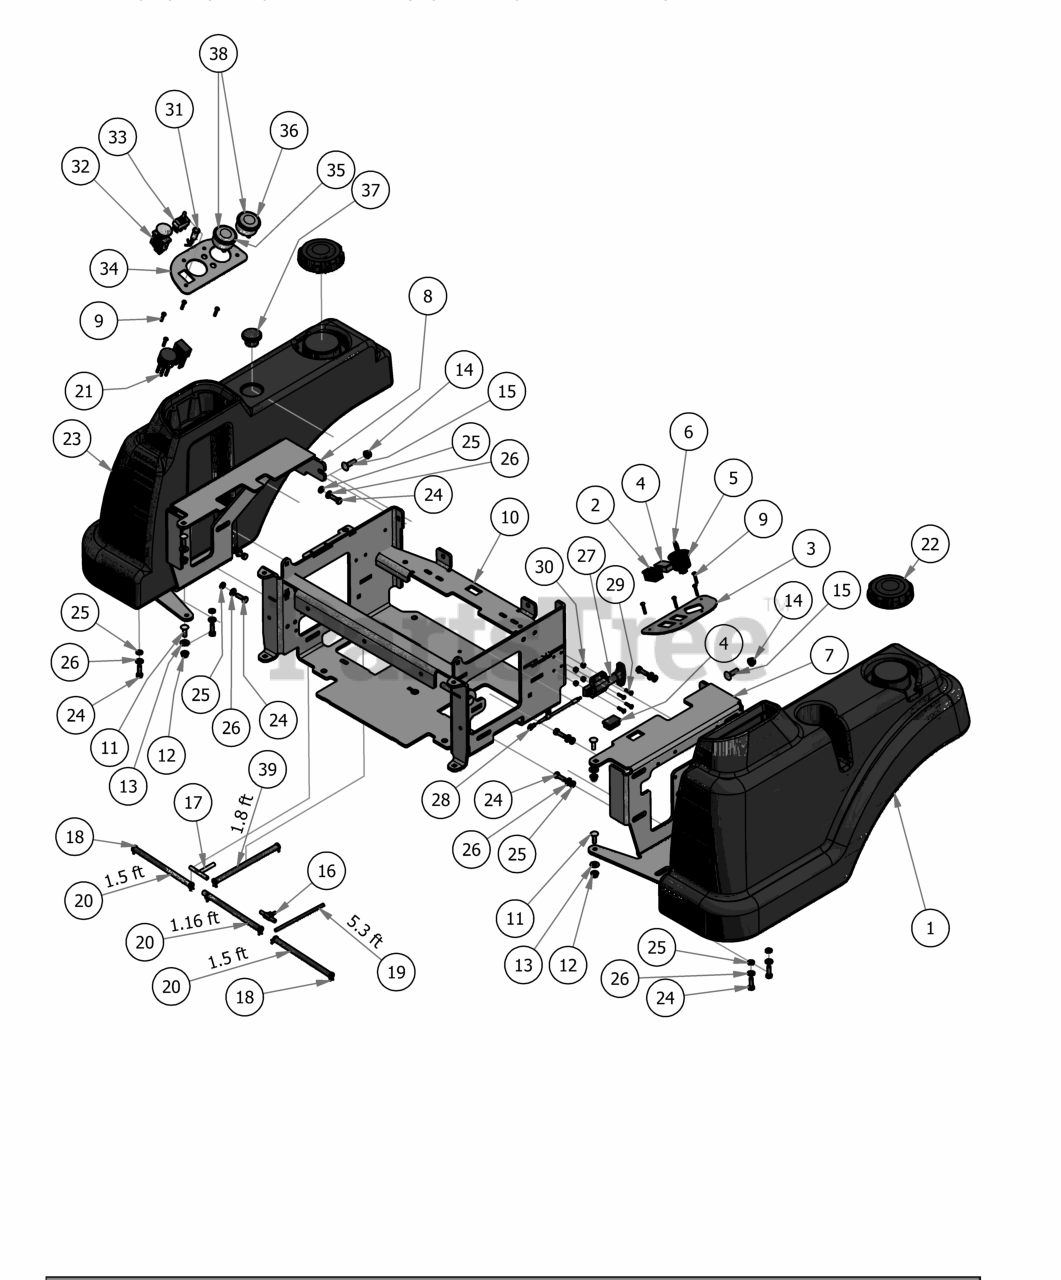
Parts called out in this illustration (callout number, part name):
1	Left Fuel Tank with Fender
2	Hour Meter
3	Control Panel (Left)
4	Light Plug
5	Ignition Switch
6	Ignition Key
7	Left Tank Support
8	Right Tank Support
9	10-32 x 1 Button Head Bolt
10	Diesel Seat Frame
11	5/16" x 1" Carriage Bolt
12	5/16" Flange Nut
13	.360 ID Plastic Washer
14	3/8" Nylock Flange Nut
15	3/8" x 1 1/4" Carriage Bolt
16	Brass fuel line T
17	fuel line T
18	1/4 Fuel Hose Clamp
19	3/16 Fuel Line
20	1/4" Fuel Line Hose
21	Wiring Harness -35 & 28 Diesel
22	Diesel Fuel Cap - 3.5" Neck
23	Right Fuel Tank with Fender
24	5/16" x 1" Bolt
25	5/16" Lock Washer
26	5/16" Flat Washer
27	2016 T Handle Release
28	2015 Seat Latch Cable
29	10-24 x 1 BS C/S 18-8 SS
30	10-24 Nylon Insert Locknut Zinc Orange Nylon
32	PTO Engager
33	Deck Lift Joystick
34	Diesel Control Panel Right 2012
35	2" Water Temperature Gauge
36	2" Oil Pressure Gauge
37	Fuel Gauge and Grommet
38	Pigtail-2" Faria Gauge -2012 & up (Used For the water and Oil Gauges)
39	5/16 Fuel Line
